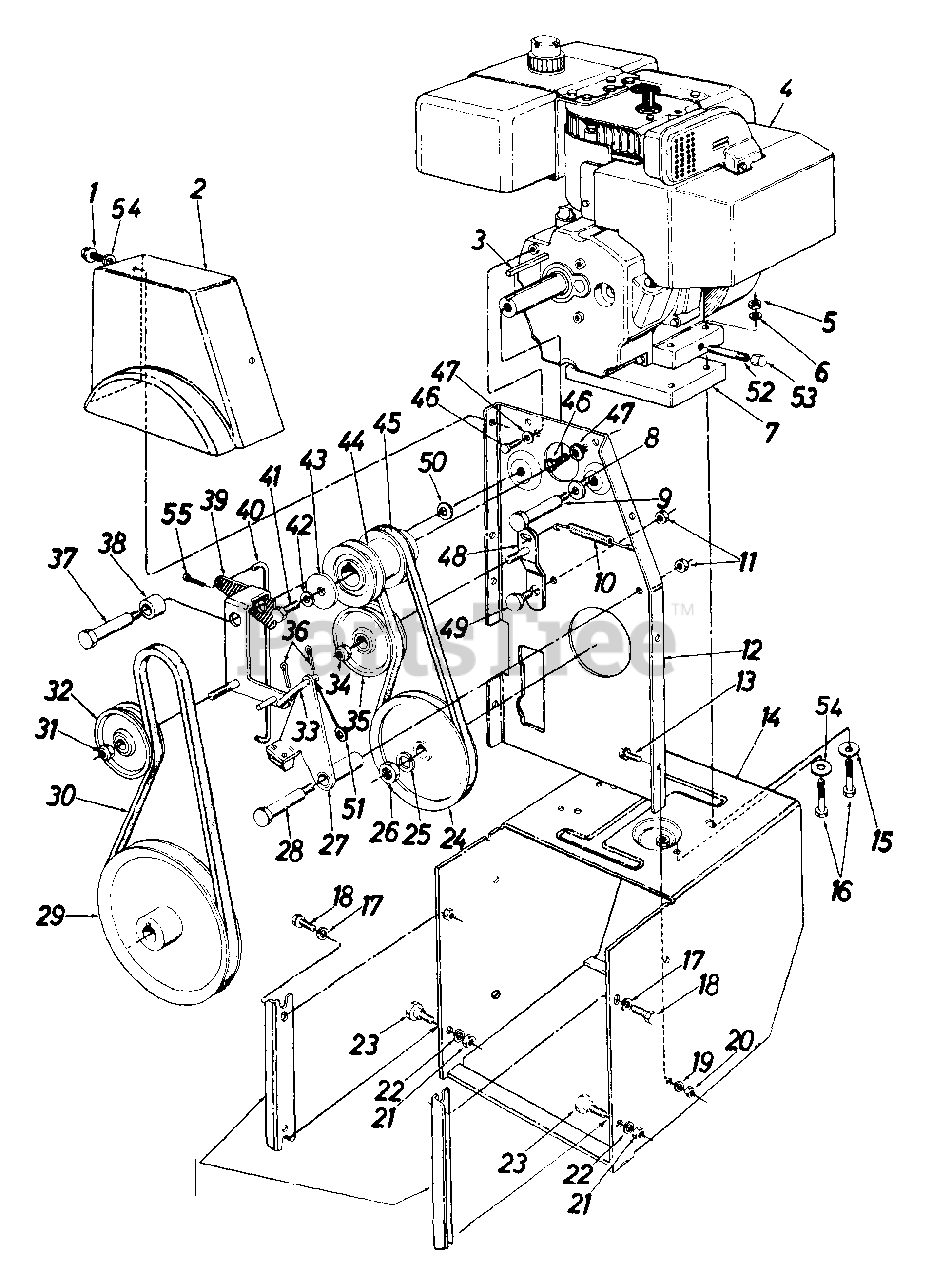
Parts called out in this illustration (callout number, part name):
1	Hex AB-Tap Scr. 5/16 x .75" Lg.
2	Belt Cover
3	Sq. Key 1/4" x 1.50" Lg.
4	Engine
5	Hex Nut 5/16-18 Thd.
6	L-Wash. 5/16" I.D.
7	Engine Spacer Ass'y.
8	Bell-Wash..40 I.D. x .88 O.D.
9	Shld. Bolt .498" Dia. x 3.00" Lg.
10	Ext. Spring .38 O.D. x 3.18" Lg.
11	Hex Cent. L-Nut 3/8-16 Thd.
12	Engine Brkt. Ass'y.
13	Hex Sems Scr. 5/16-18 x .75" Lg.
14	Frame Ass'y.
15	Fl-Wash..344" I.D. x 1.125" O.D. x .12"
16	Hex Bolt 5/16-18 x 2.25" Lg.
17	L-Wash. 3/8" I.D. H.D.
18	Pilot Scr. 3/8-16 x .88" Lg.
19	L-Wash. 5/16" I.D.
20	Hex Nut 5/16-18 Thd.
21	Hex Nut 3/8-16 Thd.
22	L-Wash. 3/8" I.D. H.D.
23	Shld. Bolt .498" Dia. x .340" Lg.
24	V-Pulley .628 I.D. x 7.50 O.D.
25	L-Wash. for 5/8" I.D.
26	Hex Ins. Jam L-Nut 5/8-18 Thd.
27	Brake Brkt. Ass'y.
28	Shld. Bolt .498" Dia. x 2.00" Lg.
29	V-Pulley .875 I.D. x 10.12 O.D.
30	"V"-Belt
31	Hex Ins. Jam L-Nut 3/8-24 Thd.
32	Fl-Idler w/Flanges 3.0 O.D.
33	Brake Linkage Ass'y.
34	Hex Ins. Jam L-Nut 3/8-24 Thd.
35	3.0" O.D. Fl-Idler w/Flanges
36	Int Cot. Pin 3/32" Dia.
37	Shld. Bolt .625" Dia x 2.750" Lg
38	Spacer .75 O.D. x 1.00" Lg.
41	Hex Bolt 3/8-24 x 1.25" Lg.
42	L-Wash 3/8" I.D. H D.
43	Fl-Wash.
44	Engine Pulley - Double Groove
45	"V"-Belt
46	Hex Bolt 5/16-24 x 62" Lg.
47	Bell-Wash. .345 I.D. x .88 O.D. x.060
48	Drive Idler Brkt Ass'y.
49	Shld. Bolt - 625" Dia x .170"
50	Bell-Wash..40 I D x 1.12 O.D.
51	Fl-Wash .385" I.D. x .620" O.D.
52	Pipe Nipple - 1/4" Pipe Thd. x 3.5" Lg.
53	Hex Hd. Cap 1/4-18 Pipe Thd.
54	Fl-Wash..344" I.D. x 62" O.D. x .63"
55	Int. Cot. Pin 5/16" Dia.
